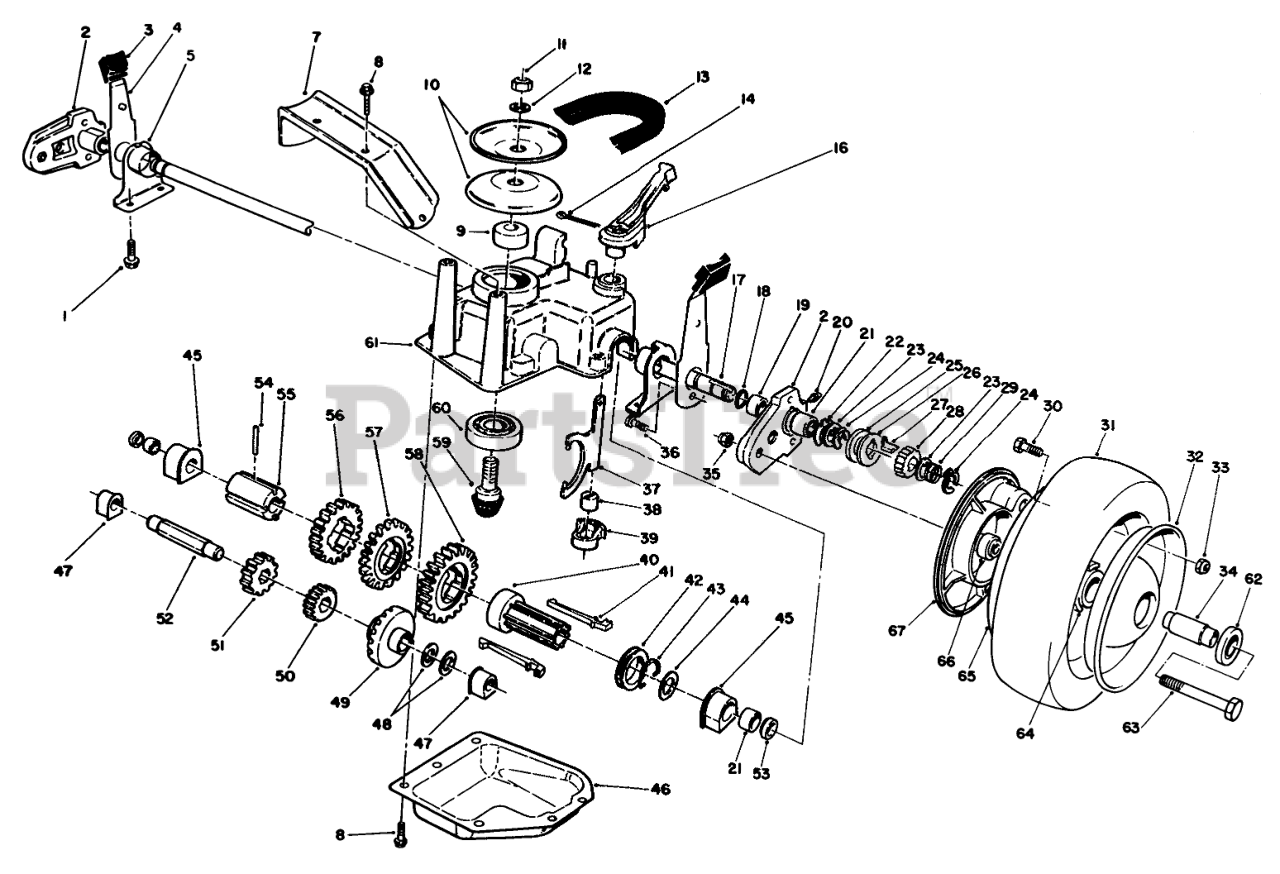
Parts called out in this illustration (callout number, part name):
1	SCREW-HWHTF
2	Pivot Arm Assembly (Incl. Ref. #19-21)
3	KNOB-ARM
4	SPRING ARM ASM
5	CAP-END
7	Bracket-BeltGuide
8	SCREW-HWHTF
9	SPACER
10	Pulley Half
11	NUT-HEX
12	WASHER-FLAT
13	V-BELT
14	PIN-COTTER
16	LEVER-SHIFT
17	OUTPUT SHAFT
18	O-RING
19	BUSHING
20	FITTING-GREASE
21	BEARING-ROLLER
22	WASHER-ARM, PIVOT
23	WASHER-THRUST, KEYED
24	RING-CLIP, LOCKING
25	RING-FRICTION
26	WASHER-CLUTCH
27	KEY-ROCKING, LH
28	GEAR-PINION
29	SPRING-COMPRESSION
30	SCREW-HH
32	Wheel-Half
33	NUT-LOCK, NI
34	SPACER-BEARING
35	NUT-LOCK, NI
36	SCREW-HSH, THREAD FORMING
37	YOKE-SHIFT
38	BUSHING-YOKE
39	RETAINER-FORK, SHIFT
40	SLEEVE-KEY, SHIFT
41	KEY-SHIFT
42	COLLAR-SHIFT
43	CLIP-SPRING
44	WASHER-PLAIN
45	OUTPUT SHAFT BUSHING
46	Cover-Gearcase
47	BUSHING
48	WASHER-THRUST
49	Gear-Bevel
50	PINION-20T
51	PINION-25T
52	SHAFT-INTERMEDIATE
53	SEAL-OIL
54	PIN-SPRING
55	SLEEVE-GEAR
56	GEAR-39T
57	GEAR-44T
58	GEAR-49T
59	Gear-Pinion
60	BEARING-BALL
61	CASE-GEAR, UPPER
62	BEARING-WHEEL
63	SCREW-HH
64	HUB-BEARING
65	Wheel-Half
66	SPACER-COVER, WHEEL
67	WHEEL COVER
